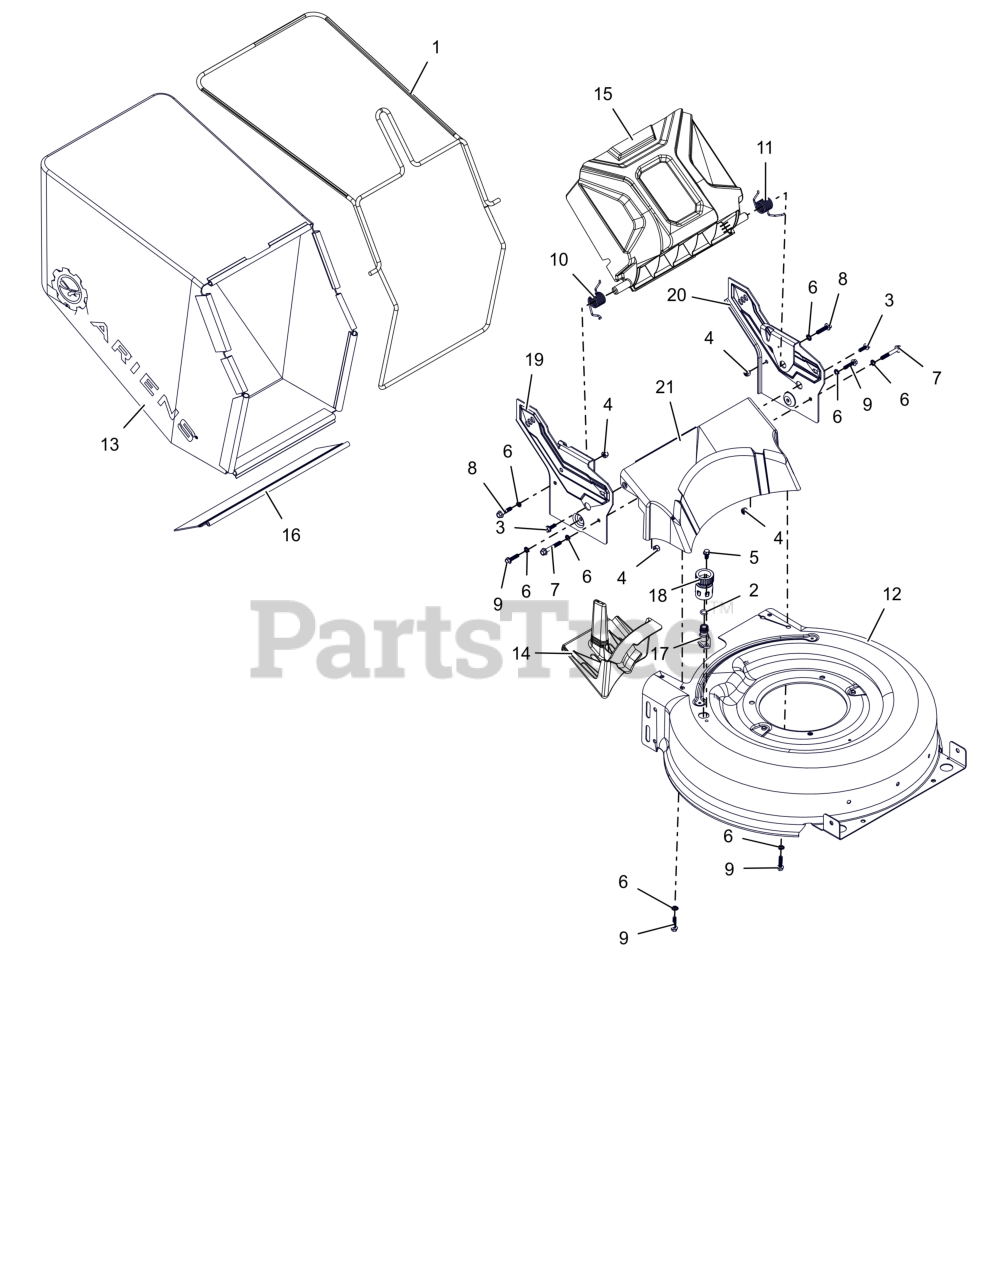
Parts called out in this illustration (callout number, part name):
1	WLDMT, BAG FRAME (ORANGE)
2	O-RING, OD .625 ID .425
3	SCR, HI-LO HWH 1/4-15 X .750
4	NUT, NYLOC 1/4-20
5	SCR, 1/4-20X.500, THREAD FORMING
6	WSHR-LK-EXT, .256X.510X.028
7	BLT, HEX 1/4-20 X 1.75 GR5
8	BLT, HEX 1/4-20 X 1.125
9	SCR, HI-LO HWH 1/4-15 X 1.00
10	SPRG, TORSION - DOOR LH
11	SPRG, TORSION - DOOR RH
12	DECK, RWD -21 (WO PORT) (ORANGE)
13	BAG, ARIENS
14	PLUG, MULCH
15	DOOR, REAR
16	GUARD, REAR DECK
17	ADAPTOR, DECK WASH OUT
18	CONNECTOR, QUICK DISCONNECT
19	BRKT, RH SIDE (BLACK)
20	BRKT, LH SIDE (BLACK)
21	COVER, BACK - FWD
